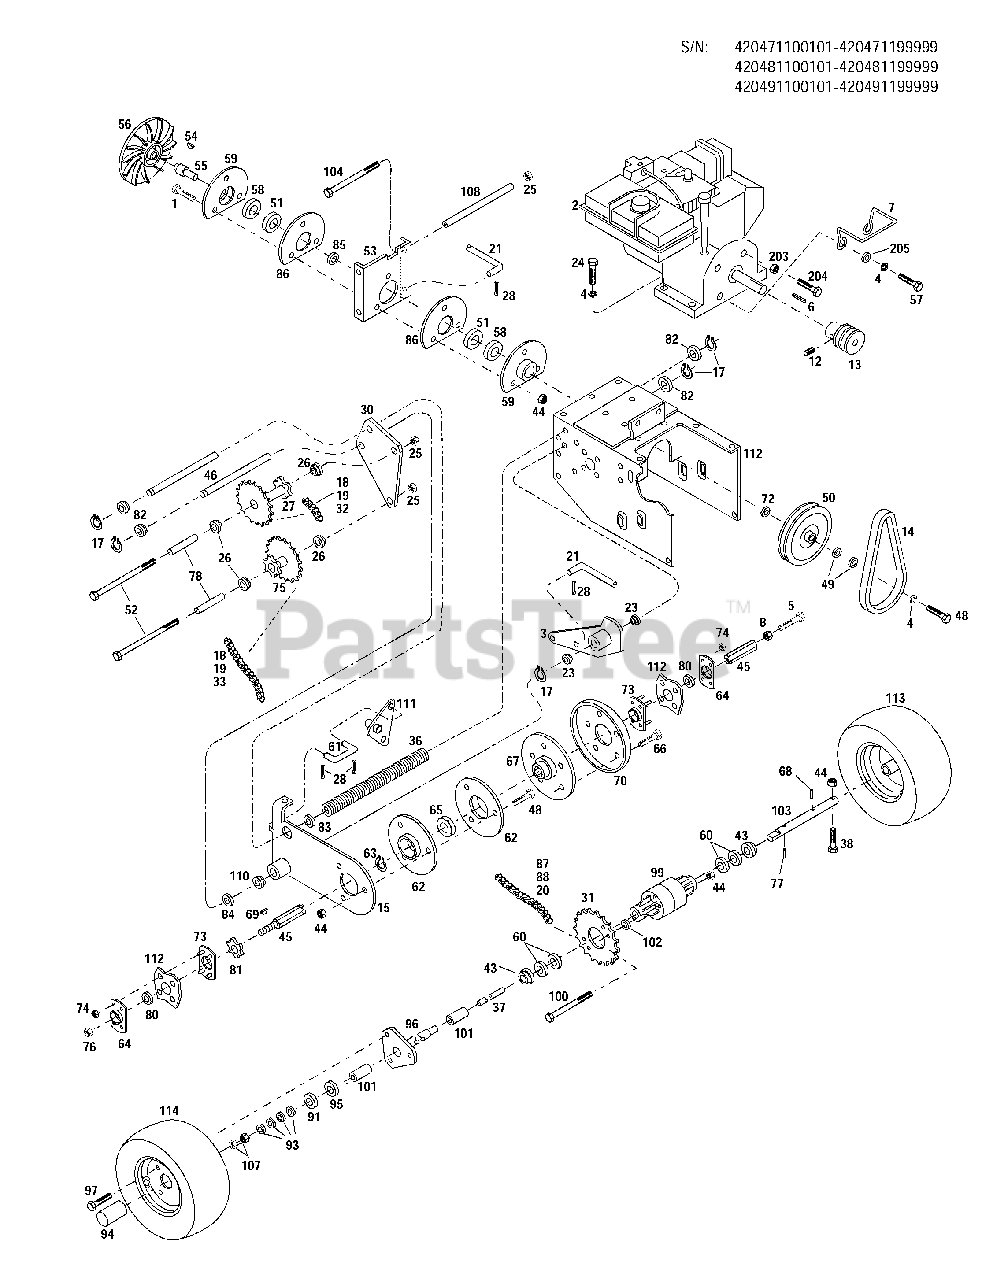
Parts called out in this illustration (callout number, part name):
1	Hex Bolt, 5/16-18 x 1
2	Tecumseh Engine, 8 HP
3	Control Arm
4	Lock Washer, 5/16
5	Shoulder Bolt, 3/8-16 x 1-1/2
6	Square Key, 1/4 x 2-1/4
7	Belt Guide
8	Bushing
12	Set Screw, 5/16-18 x 5/8
13	Engine Sheave
14	V-Belt
15	Drive Support
17	Retaining Ring
18	Offset Link (Half Link)
19	Connecting Link, #41
20	Final Drive Chain #40
21	Control Link
23	Flange Bushing
24	Hex Head Bolt, 5/16-18 x 1-1/2
25	Flange Lock Nut, 3/8-16
26	Flange Bearing
27	Sprocket Assembly, 9T/17T
28	Cotter Pin, 3/32 x 3/4
30	Support Plate
32	Drive Chain
33	Drive Chain
36	Compression Spring
38	Hex Head Bolt, 5/16-18 x 1-3/4
43	Flange Bushing, 7/8
44	Lock Nut, 5/16-18
45	Hex Shaft
46	Shaft Support
48	Cap Screw, 5/16-18 x 3/4
49	Special Flat Washer
50	Wheel Drive Sheave
51	Ball Bearing
52	Capscrew, 3/8-16 x 3-1/2
53	Drive Disc Support
54	Woodruff Key, 3/16 x 5/8
55	Spindle
56	Drive Plate
57	Hex Head Bolt, 5/16-24 x 1
59	Bearing Retainer
60	Flat Washer, 7/8
61	Connecting Link
62	Bearing Retainer
63	Snap Ring
64	Bearing Flange
65	Ball Bearing
66	Flange Bolt, 5/16-18 x 1/2
67	Friction Disc Hub
68	Drive Pin, 3/16 x 1-1/2
69	Woodruff Key
70	Molded Friction Disc
72	Special Washer
73	Bearing Flange Assembly
74	Lock Nut, #10-24
75	Sprocket Assembly, 9T/30T
76	Jam Nut, 1/2-13
77	Drive Pin
78	Spacer
80	Ball Bearing
81	Sprocket, 9T
82	Nylon Bushing
83	Special Flat Washer
84	Flat Washer, 5/8
86	Bearing Retainer
87	Connecting Link
88	Offset Link (Half Link)
91	D-Hole Drive Washer
93	Disc Spring
94	Dust Cap
95	Friction Disc
96	Flange & Axle Tube Assembly
97	Lug Bolt
99	Differential Assembly
101	Nylon Bushing
102	Spacer
103	Axle Shaft
104	Hex Head Bolt, 3/8-16 x 8-1/2
107	Jam Nut, 1/2-13
108	Tubular Spacer
110	Flange Bearing
111	Speed Control Arm
112	Frame
113	Wheel & Tire Assembly
114	Wheel & Tire Assembly
203	Hex Nut, 5/16-24
204	Screw, Hex Cap, 5/16-24 x 4-1/2
205	Flat Washer, 5/16
